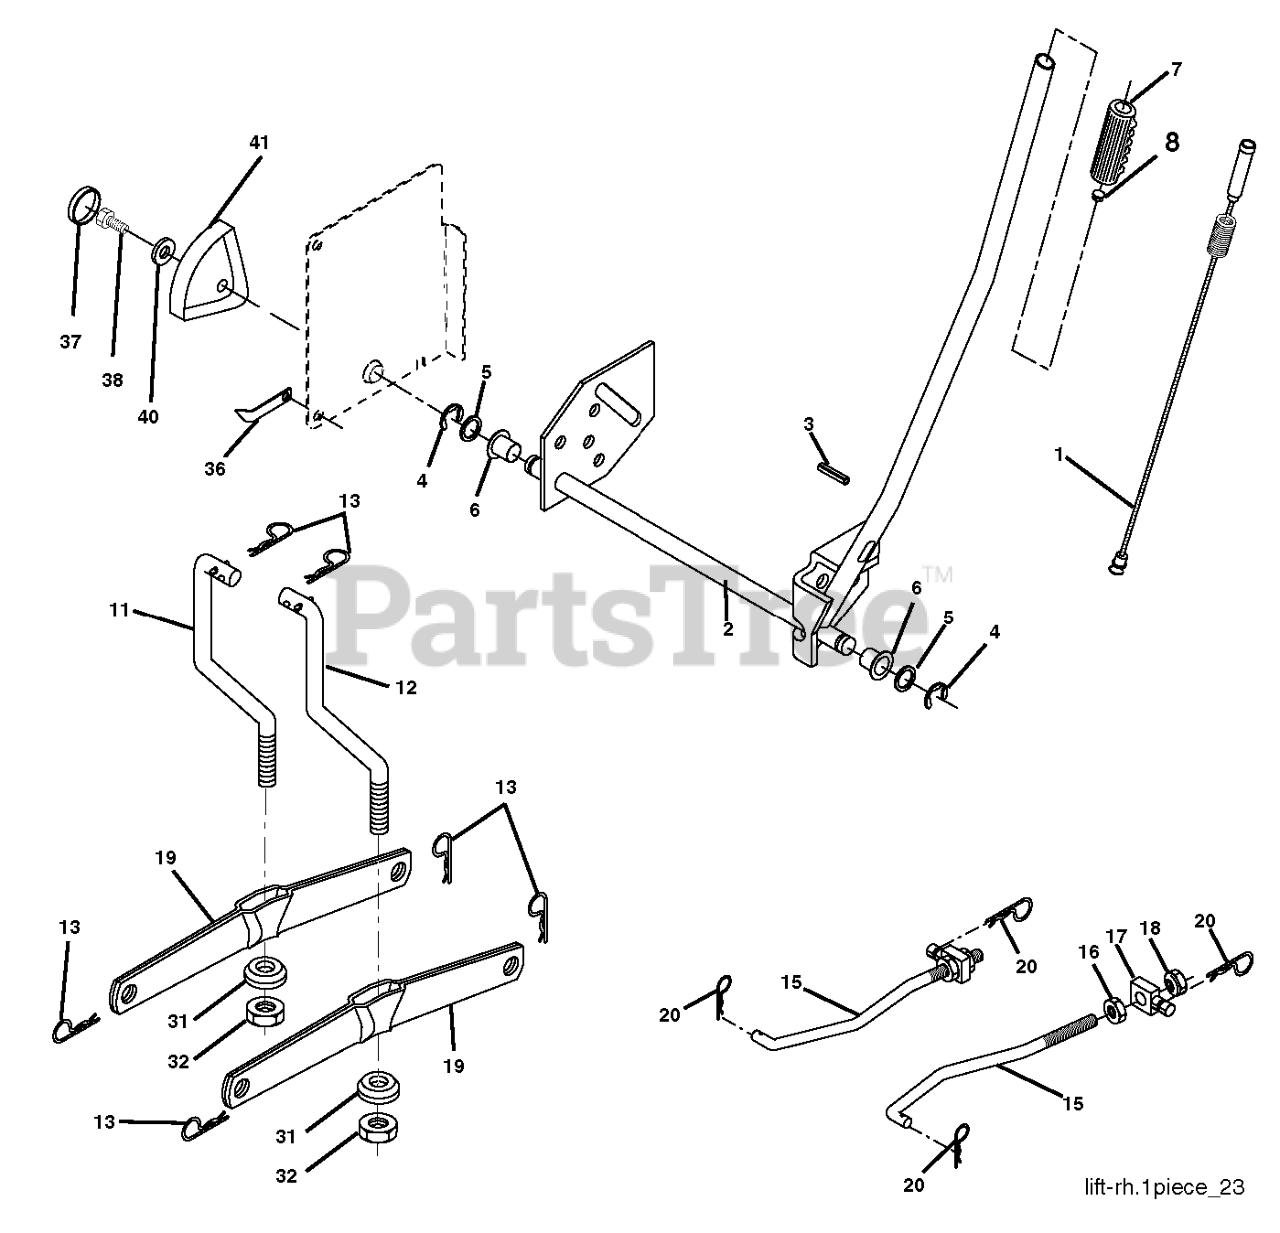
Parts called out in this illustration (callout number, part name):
1	WIRE ASM INNER W/ PLUNGER LT
2	SHAFT ASM R HANDLE
3	PIN GROOVE.
4	RETAINING RING LT
6	BEARING.NYLON
7	GRIP HANDLE
8	PLUNGER BUT KIT
11	LINK LIFT LH
12	LINK LIFT RH
13	RETAINER-SPRNG RB
15	LINK.SUSPENSION.FRONT
16	NUT.HEX.JAM.1/2-13
18	NUT.LK.W/WSH.1/2.
19	ARM.REAR.SUSPENSION
20	PIN.COTTER.7/16.BOW TI.
31	BEARING.PIVOT.LIFT
32	NUT CROWNLOCK 3/8-24
36	POINTER, HEIGHT INDICATOR(2 2)
38	SCREW 5/16-18X1
41	IND. HEIGHT STLT
